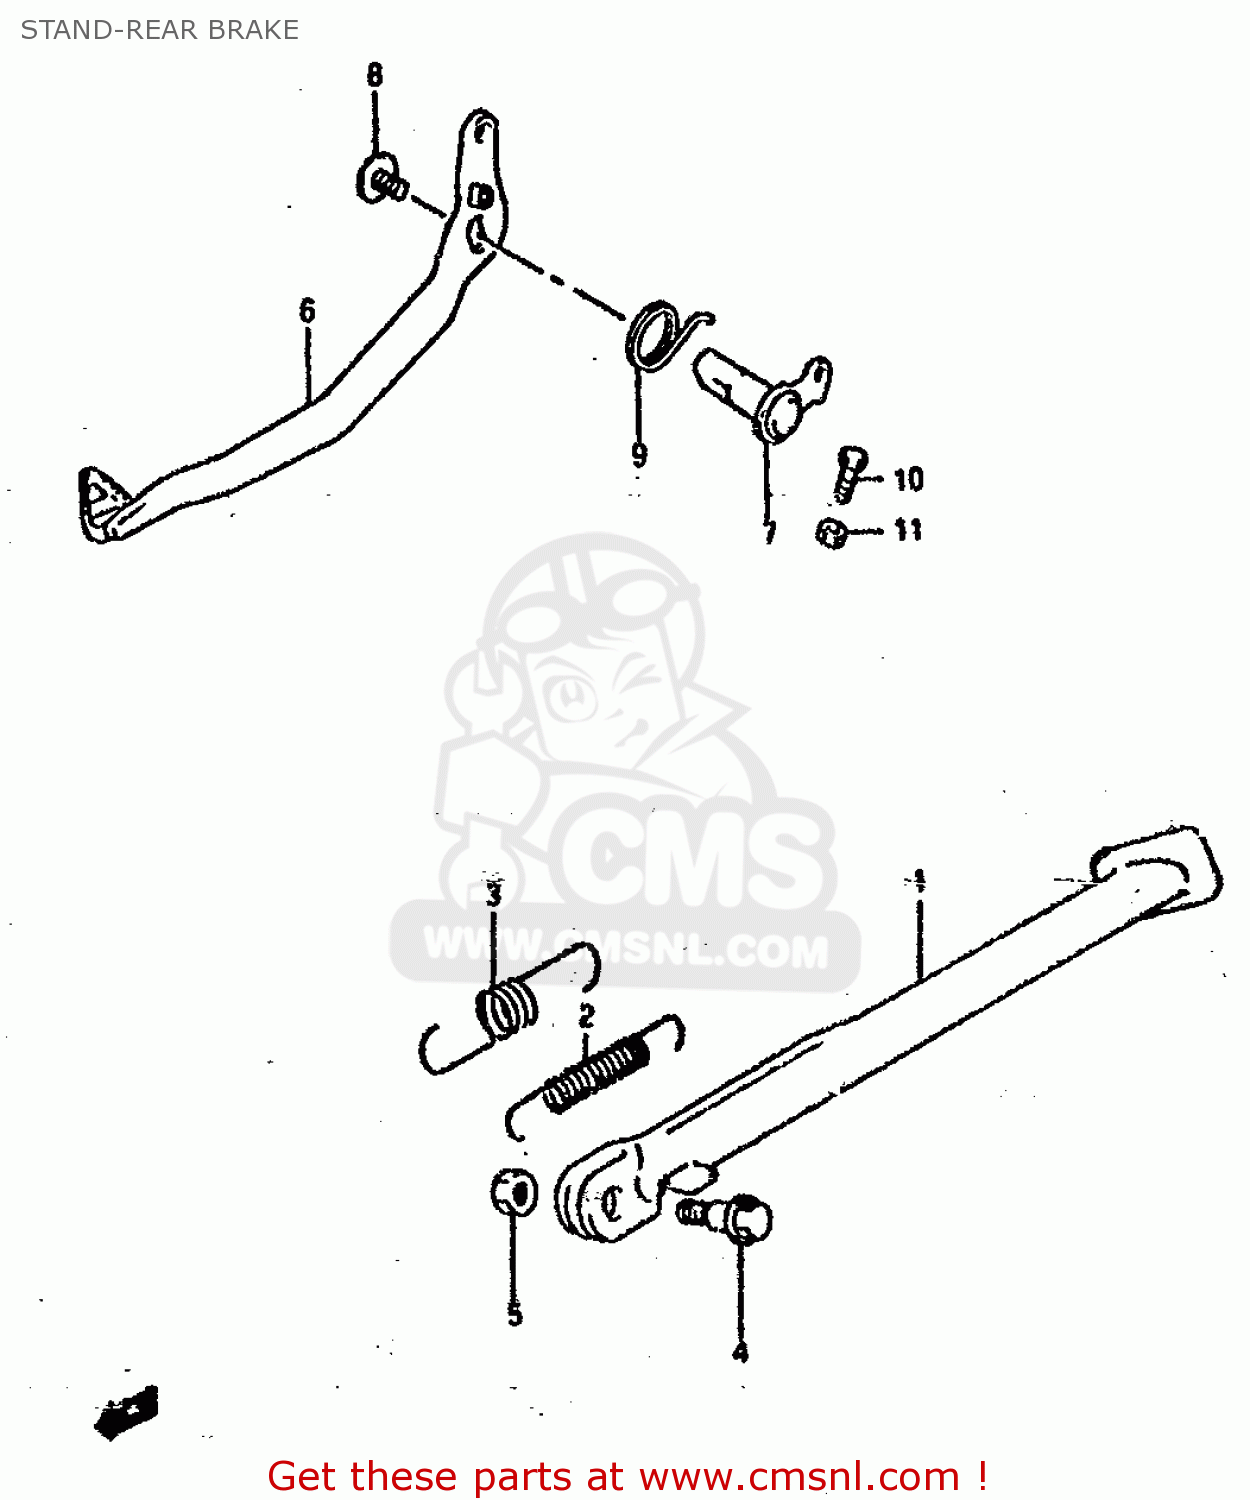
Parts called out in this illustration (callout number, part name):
1	STAND,PROP (BLACK)
2	SPRING
3	SPRING
4	BOLT(10X33.5)
5	NUT
6	PEDAL,BRAKE
7	ARM,BRAKE PEDAL ROD
8	BOLT 8X14
9	SPRING
10	BOLT(6X23)
11	NUT 6MM
